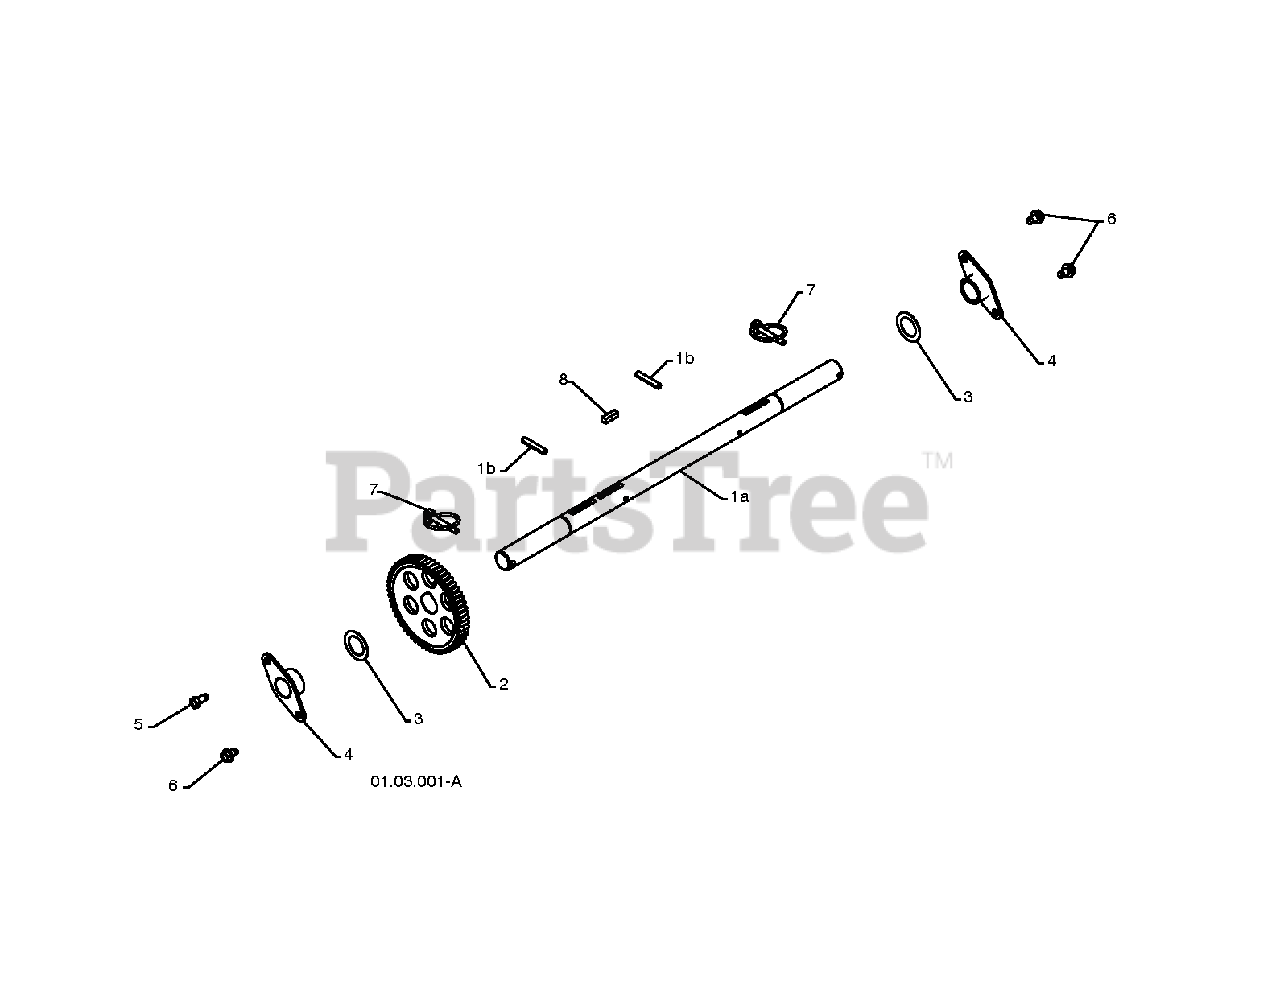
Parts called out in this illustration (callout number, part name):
1	AXLE.ASM.SHAFT.W/ROLLPIN.PS
2	GEAR, AXLE (58T)
3	WASHER TRUST 1"
4	BEARING, AXLE
7	PIN KLIK, 1/4
8	KEY, SQUARE 1/4 X .875
